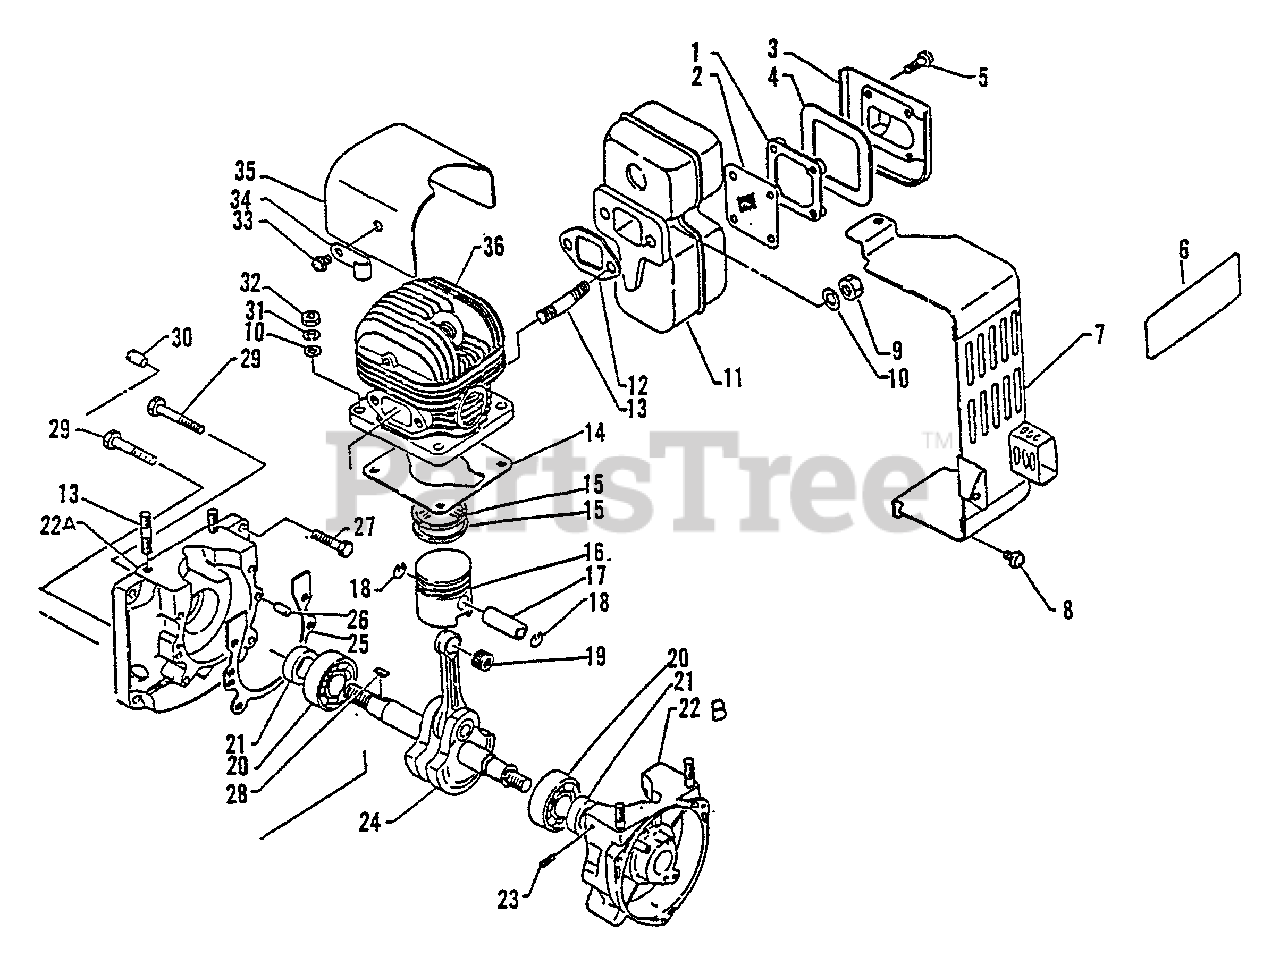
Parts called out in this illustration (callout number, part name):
1	SEAT, SCREEN
2	SCREEN, SPARK ARRESTER
3	GUIDE, EXHAUST
4	GASKET, EXHAUST
5	SCREW 4×14
6	LABEL - CAUTION
7	COVER, EXHAUST
8	SCREW 5×14
9	NUT, LOCK 6
10	WASHER 6.5×11.5×0.8
12	GASKET, EXHAUST
14	GASKET, CYLINDER
15	RING, PISTON
16	PISTON KIT
17	PIN, PISTON
18	RING, SNAP 8
19	BEARING, NEEDLE
20	BEARING, BALL 6202
21	SEAL, OIL
22	CRANKCASE KIT
23	CONNECTOR
24	CRANKSHAFT ASSY
25	GASKET, CRANKCASE
26	PIN, LOCATING 5×10
31	WASHER, SPRING 6
32	NUT, HEX M6
33	BOLT 6×10
34	CLIP, CORD
35	COVER, CYLINDER
36	CYLINDER
